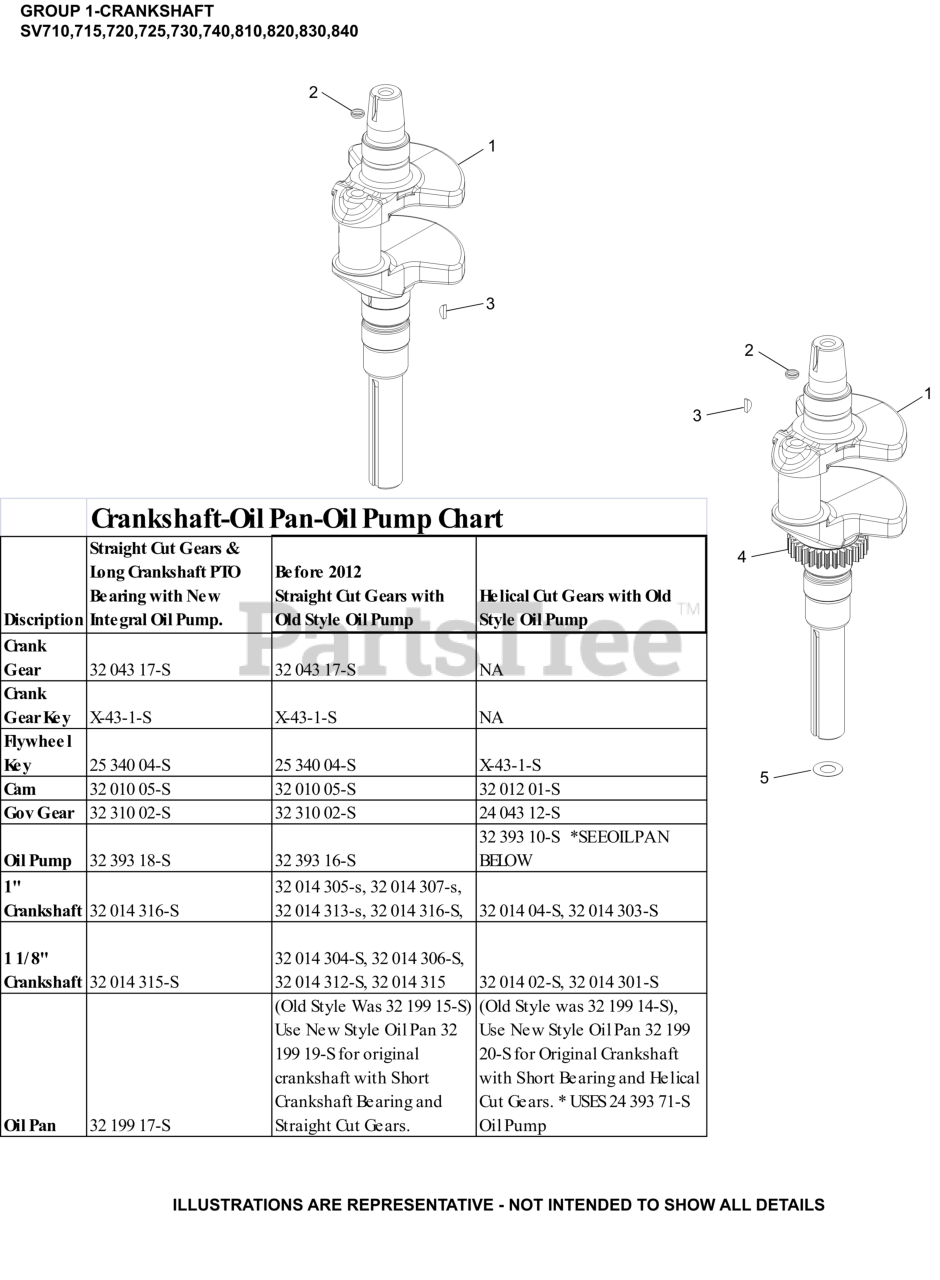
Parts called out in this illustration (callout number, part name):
1	CRANKSHAFT ASSY-USE 32 014 327-S
2	PLUG, CUP
3	KEY, 1/8" X 1/2"
4	GEAR, CRANKSHAFT
5	SPACER (.010")
